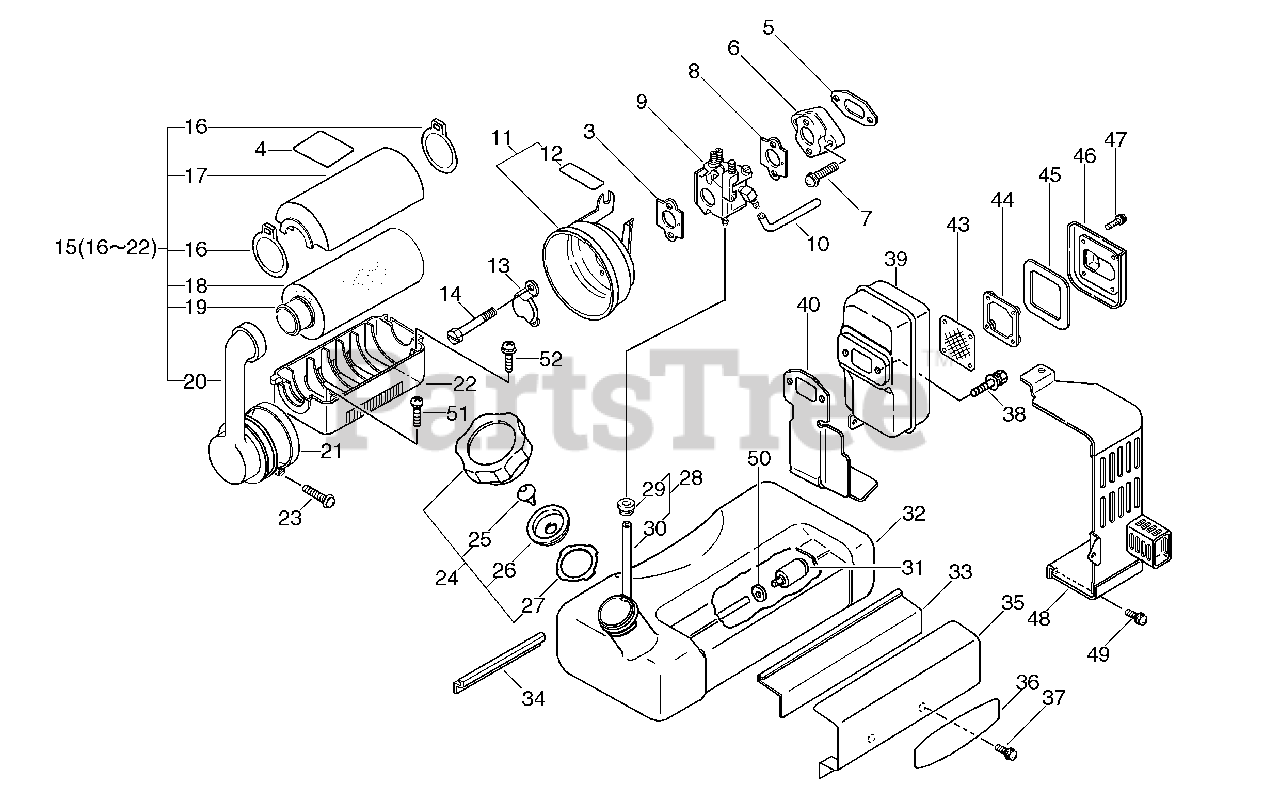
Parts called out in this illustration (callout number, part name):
3	GASKET, INTAKE
4	LABEL - CAUTION
5	GASKET, INTAKE
6	INSULATOR
7	SCREW 6×25
8	GASKET, CARBURETOR
9	CARBURETOR - WT-410C
10	PIPE
11	CASE, AIR FILTER
12	LABEL - CHOKE
13	PLATE, PREVENT
14	SCREW 5×50
15	AIR FILTER ASSY
17	COVER, AIR FILTER
18	FILTER, AIR
19	HOLDER, AIR FILTER
20	ADAPTER, INTAKE
22	CASE, AIR FILTER
23	SCREW 5×30
24	CAP ASSY
25	VENT ASSY
26	HOLDER, CHECK VALVE
27	GASKET, FUEL CAP
28	PIPE, FUEL W/GROMMET 3×5×250L
30	PIPE, FUEL W/GROMMET 3×5×250L
31	FILTER, FUEL
32	TANK, FUEL
33	CUSHION, FUEL TANK
34	CUSHION, FUEL TANK
35	BRACKET, FUEL TANK
36	LABEL - ECHO
37	SCREW 5×10
38	BOLT 6×20
40	GASKET, EXHAUST
43	SCREEN, SPARK ARRESTER
44	SEAT, SCREEN
45	GASKET, EXHAUST
46	GUIDE, EXHAUST
47	SCREW 4×16
48	COVER, MUFFLER
49	SCREW 5×14
50	CLIP 6 MM
51	SCREW 6×15
52	SCREW 6×20
